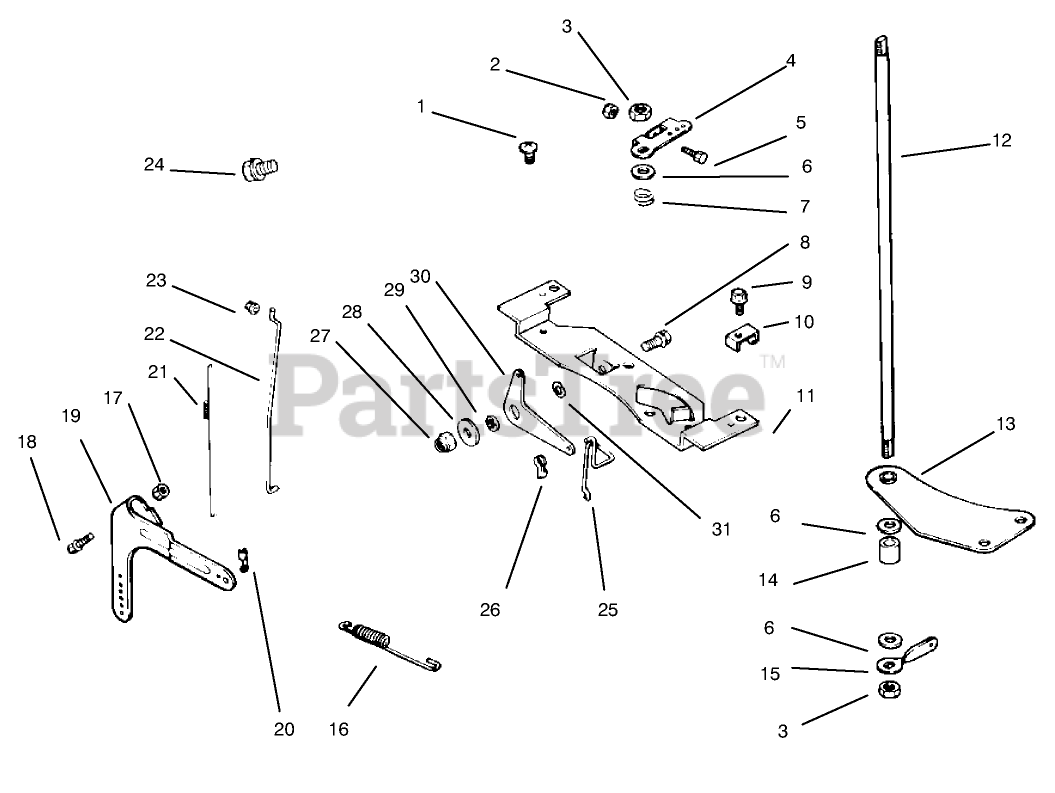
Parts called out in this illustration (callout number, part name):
1	Screw
2	Nut
3	Nut
4	Lever-Throttle Control
5	Screw
6	Washer
7	Spring-Throttle Shaft
8	Screw
9	Screw
10	Clamp
11	Bracket-Control
12	Shaft-Throttle
13	Bracket-Throttle Shaft
14	Spacer
15	Lever-Throttle Control
16	Spring-Governor
17	Nut
18	Screw
19	Lever-Govenor
20	Bushing-Linkage
21	Spring-Linkage
22	Linkage-Throttle
23	Bushing-Linkage
24	Screw
25	Linkage-Choke
26	Bushing-Linkage
27	Nut
28	Washer
29	Spacer
30	Lever-Choke
31	Washer
